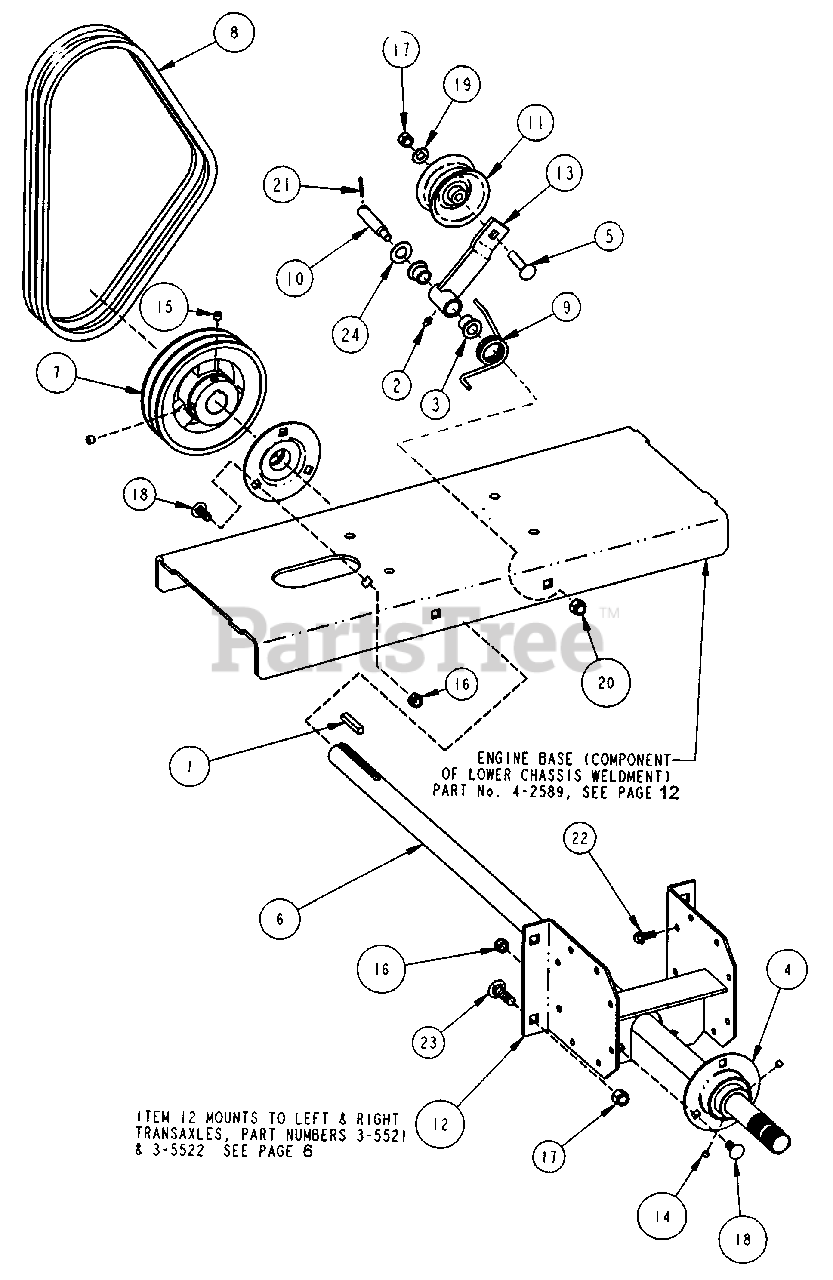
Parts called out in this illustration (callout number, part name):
1	KEY, 1/4" Square x 2"
2	LUBE FITTING, Straight (press-fit for .187 dia. Hole)
3	BUSHING
4	BEARING
5	BOLT, 3/8-16 x 1-3/4" Carriage, Grade 5
6	DRIVE SHAFT, Deck
7	PULLEY, Double V
8	BELT, Deck Drive (HA 36.5)
9	SPRING, Tension
10	PIN, 3/8-24 UNF
11	FLAT IDLER, 2.75 O.D. x 1-1/4" Wide
12	BEARING MOUNT (Weldment)
13	IDLER ARM, Offset (Weldment)
14	SET SCREW, 1/4-20 x 1/4" Cone Point
15	SET SCREW, 5/16-18 x 5/16 Type C
16	NUT, 5/16-18 HEX NYLON LOCK
17	NUT, 3/8-16 HEX NYLON LOCK
18	BOLT, 5/16-18 x 3/4, Grade 5
19	WASHER, 3/8" Flat
20	NUT, 3/8-24 Hex Nyloc
21	COTTER-PIN, 1/8 x 3/4"
22	SCREW, 1/4-20 x 5/8", Hex Flange Lock, Grade 5
23	BOLT, 3/8-16 x 1-1/4" Carriage, Grade 5
24	WASHER, 9/16 Flat
